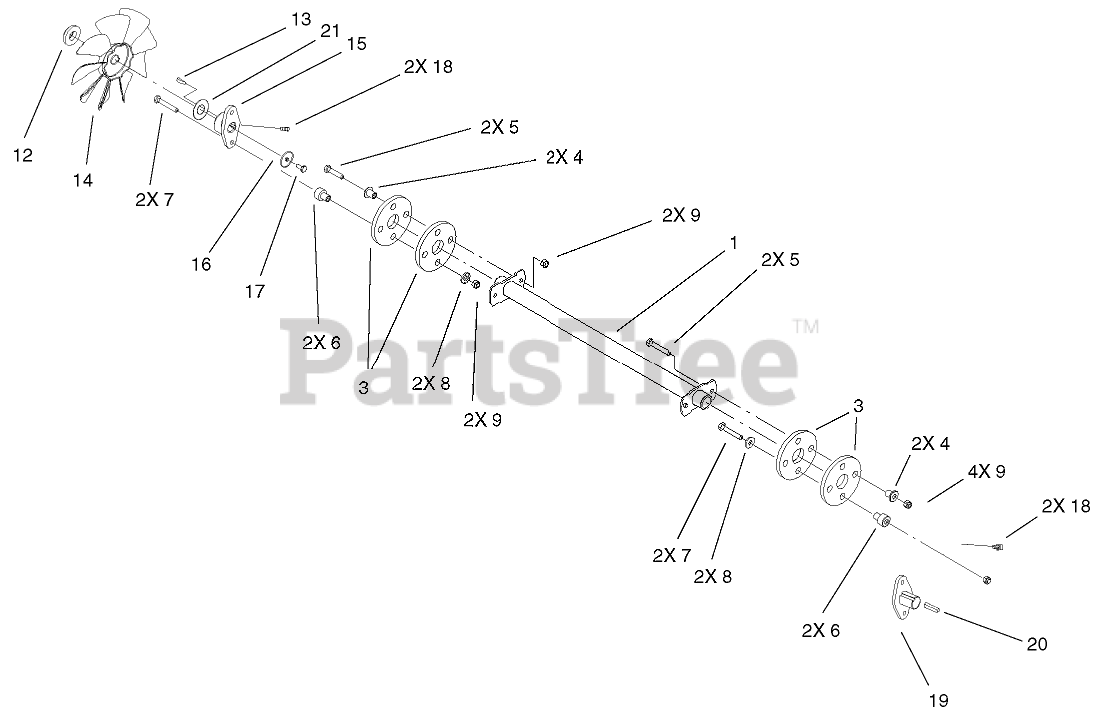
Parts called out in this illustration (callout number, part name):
1	SHAFT-DRIVE
3	COUPLING-RUBBER
4	SPACER
5	SCREW-HH
6	SPACER
7	SCREW-HH
8	WASHER-FLAT
9	NUT-LOCK, NI
12	SPACER-FAN
13	KEY-WOODRUFF
14	FAN-HYDRO
16	WASHER
17	SCREW-HH
18	SCREW-SET
19	WA - PIN DRIVE
21	WASHER - FAN
